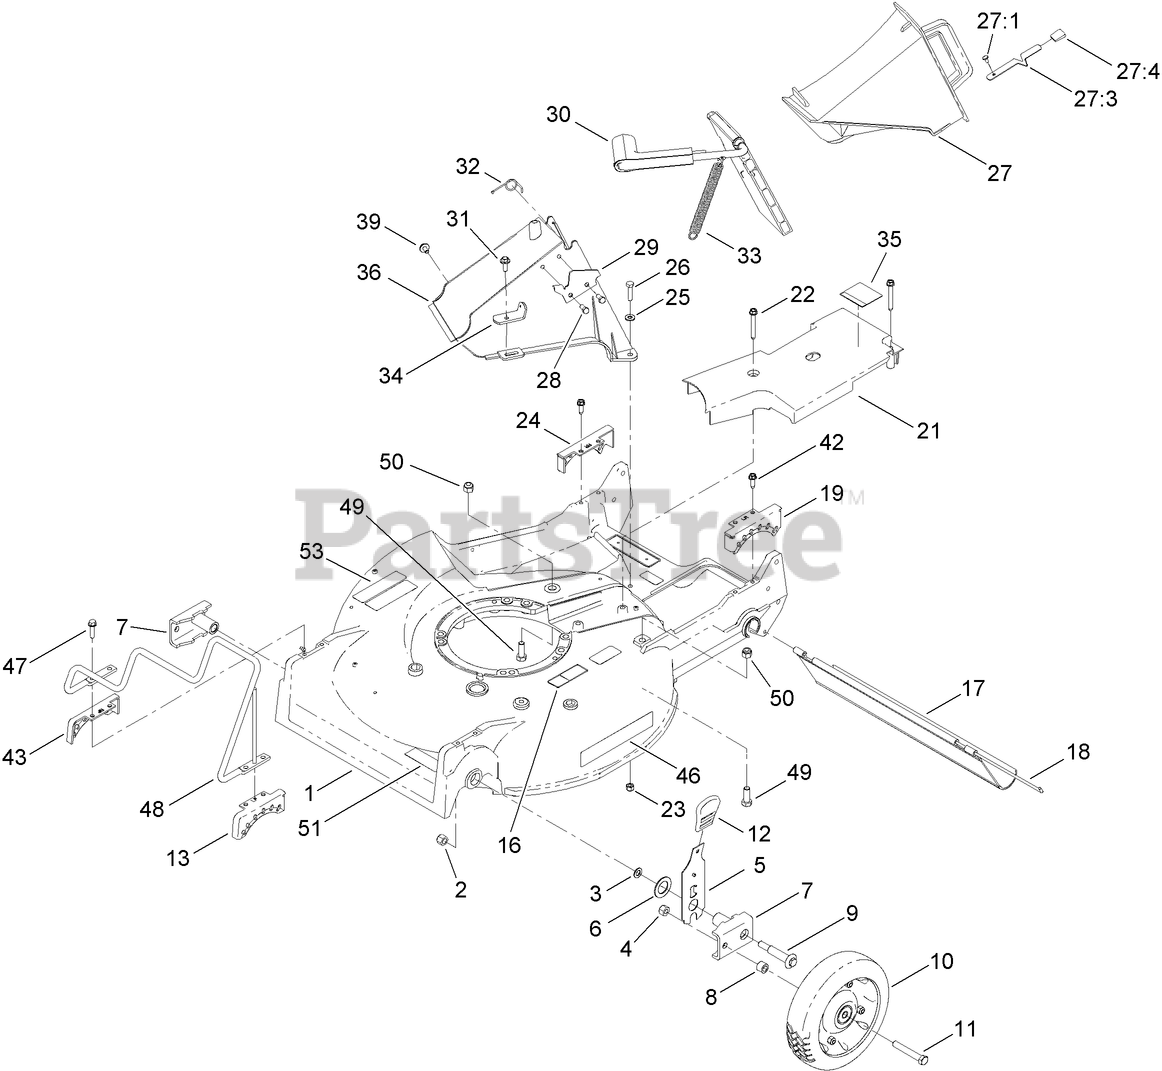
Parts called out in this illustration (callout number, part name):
1	HOUSING ASM
2	NUT-LOCK
3	WASHER
4	NUT-LOCK, CONE
5	FRONT SPRING ARM ASM
6	WASHER-THRUST
7	ARM-PIVOT, FRONT
8	SPACER-WHEEL
9	SCREW-SHOULDER
10	WHEEL AND TIRE ASM
11	SCREW-HH
12	KNOB-HOC
13	QUADRANT-FRONT, LH
16	DECAL-WARNING, BLOCK
17	SHIELD-TRAILING
18	ROD-SHIELD
19	QUADRANT-REAR, LH
21	COVER-BELT
22	SCREW-HWHTF
23	NUT-LOCK, NI
24	QUADRANT-REAR, RH
25	WASHER-FLAT
26	SCREW-HH
27	DISCHARGE PLUG ASM
27:1	RIVET-HEAD, FLAT
27:3	LATCH-PLUG, DISCHARGE
27:4	GRIP-LATCH
28	SCREW-PLASTITE
29	LATCH-PLATE
30	DISCHARGE DOOR ASM
31	SCREW-HWH
32	RETAINER-DOOR
33	SPRING-DOOR
34	BRACKET-SPRING
35	DECAL-GREASE
36	TUNNEL-DISCHARGE
39	SCREW AND WASHER ASM
42	SCREW-HWHTF
43	QUADRANT-FRONT, RH
47	SCREW-HWHTF
48	GUARD-ENGINE
49	SCREW-HH
50	NUT-LOCK, NI
51	DECAL-BLADE
53	DECAL-ARRESTER, SPARK
